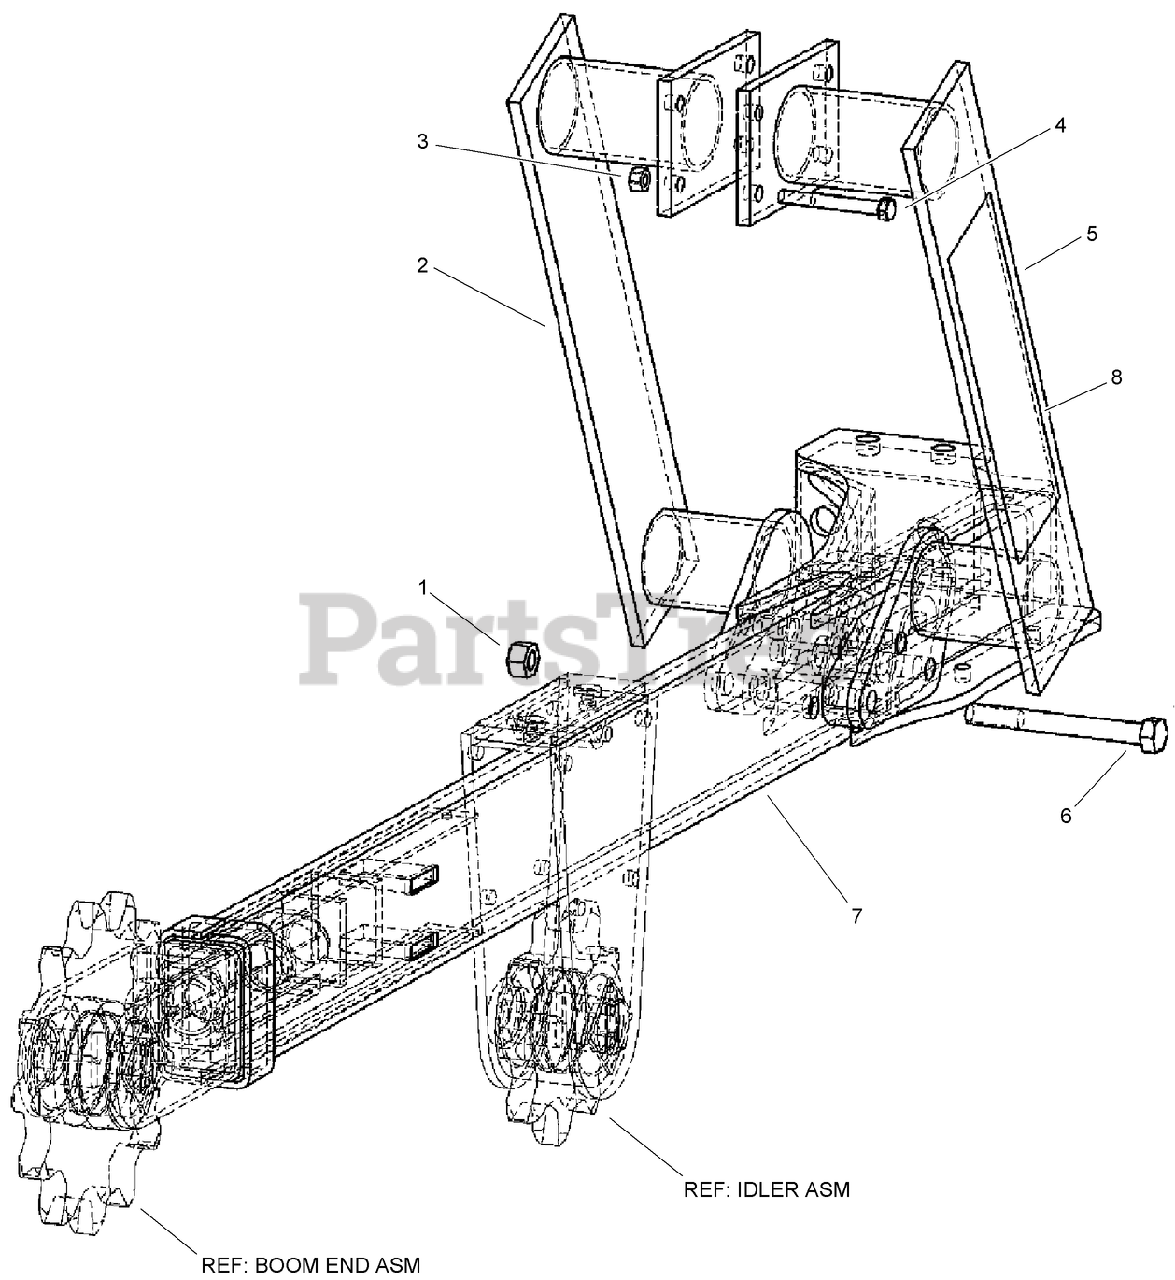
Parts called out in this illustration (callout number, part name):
1	NUT-Prev Trq 3/4 GRC CAD Direct
2	MOUNT-Crumber, LH
3	NUT-HEX
4	SCREW-HH
5	MOUNT-Crumber, RH
7	BOOM-trencher, 5 foot, heavy duty planetary drive trencher
8	DECAL-Danger, Sharp Parts (large)
